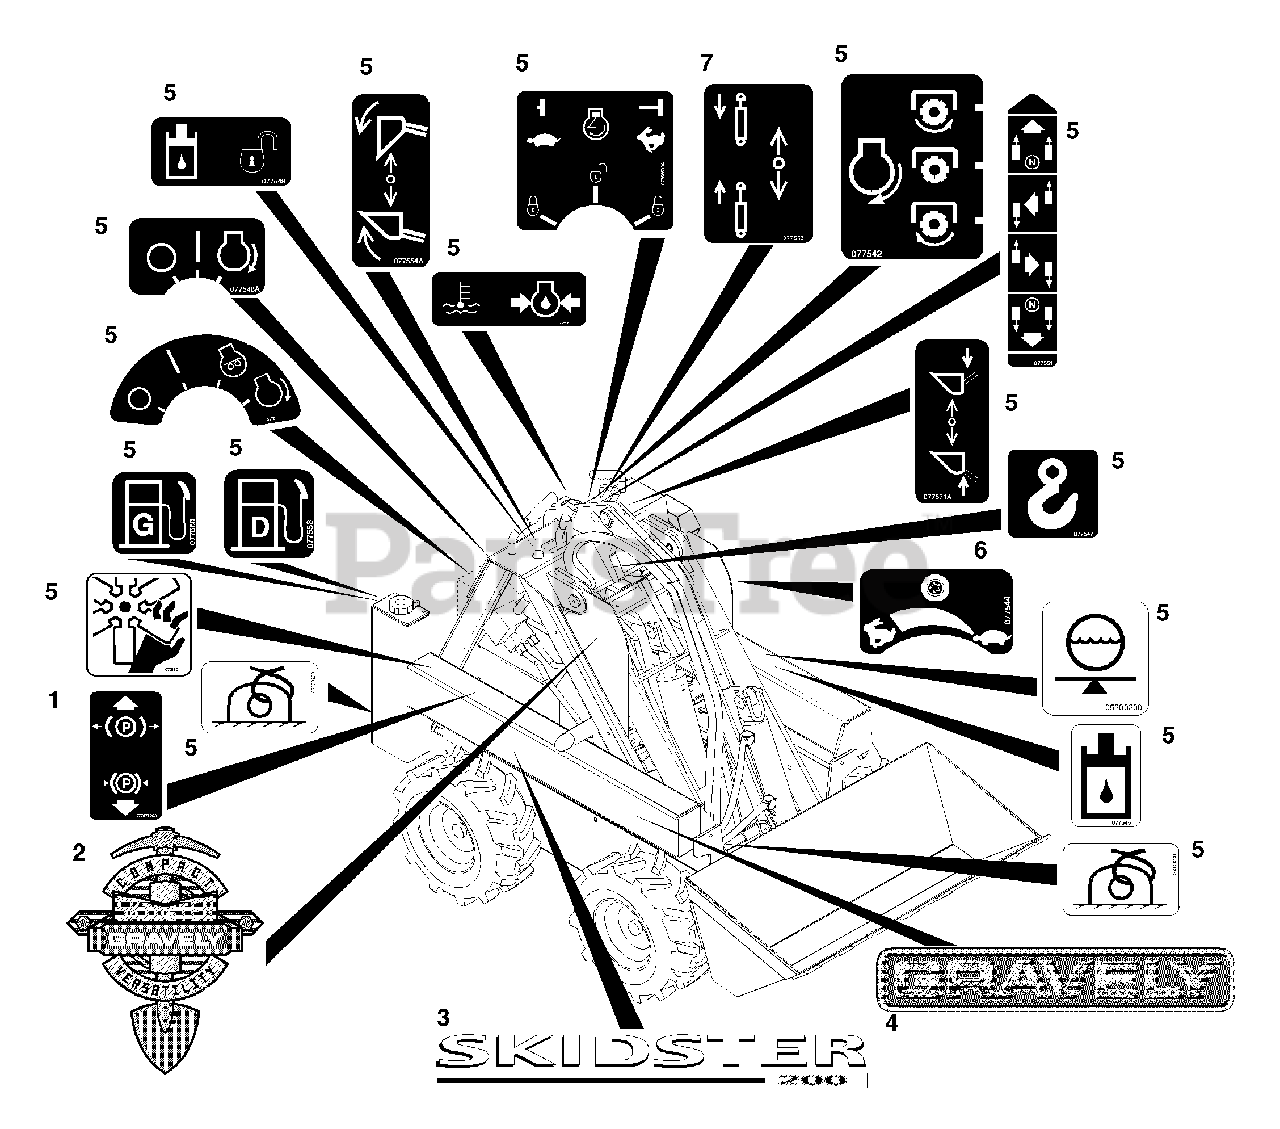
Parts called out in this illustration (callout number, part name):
1	Decal-Parking Brake Lever
2	Decal-Skidster Icon
3	Decal-Skidster 200
3	Decal, Skidster 200D
4	Decal-Gravely
5	Set, Decal
6	Decal-Ground Speed Control
7	Decal-Hydraulic Control
